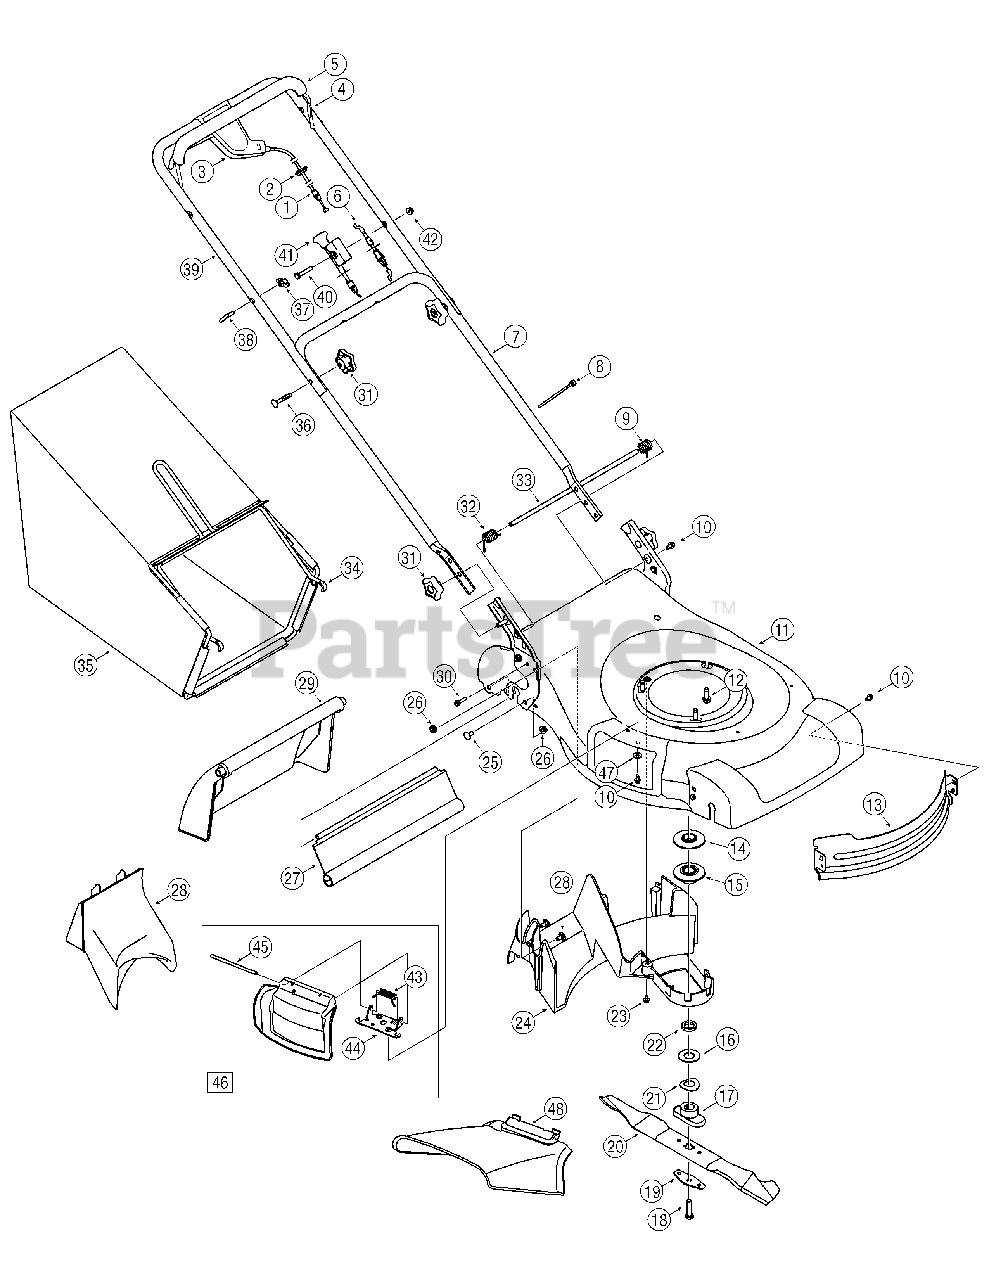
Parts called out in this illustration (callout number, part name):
1	Drive Control Cable
2	Rubber Grommet
3	Drive Control Assembly
6	ERS Control Cable
9	Torsion Spring, LH
10	TT Screw, 1/4-20 x .500
12	TT Screw, 3/8-16 x 1.00
13	Deck Baffle
14	Upper Engine Pulley
15	Lower Engine Pulley
16	Flat Washer, .885 x 1.850 x .060
17	Blade Adapter
18	Screw, 3/8-24 x 1.50
19	Blade Bell Support
20	21-inch Mulching Blade
21	Spring Washer, .890 x 1.70
22	Sleeve Spacer
23	TT Screw, 1/4-20 x .375
24	Deck Baffle
25	Carriage Bolt, 5/16-18 x .62
26	Flange Lock Nut, 5/16-18
27	Trail shield
29	Rear Door
30	Screw, 1/4-15 x 1.00
31	Star Knob
32	Torsion Spring, RH
33	Door Pivot Rod
36	Carriage Bolt, 5/16-18 x 2.00
41	Choke Control Cable
42	Flange Lock Nut, 1/4-20
43	Torsion Spring
44	Chute Deflector Adapter
45	Hinge Pin
46	Mulch Plug Assembly
47	Bell Washer, .265 x .75 x .062
48	Side Discharge Chute
